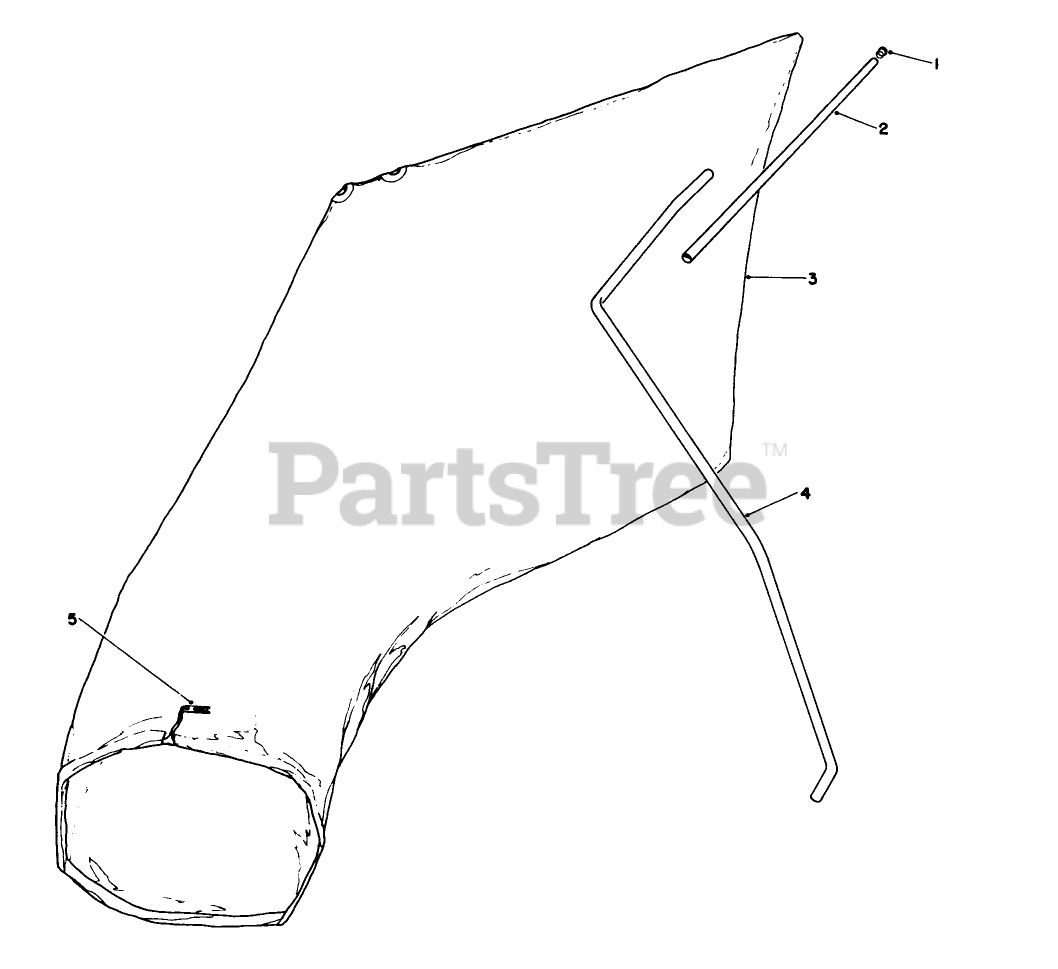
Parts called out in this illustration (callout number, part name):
2	BAG HANGER TUBE
4	HANGER ROD
5	BAG CORD FASTENER
